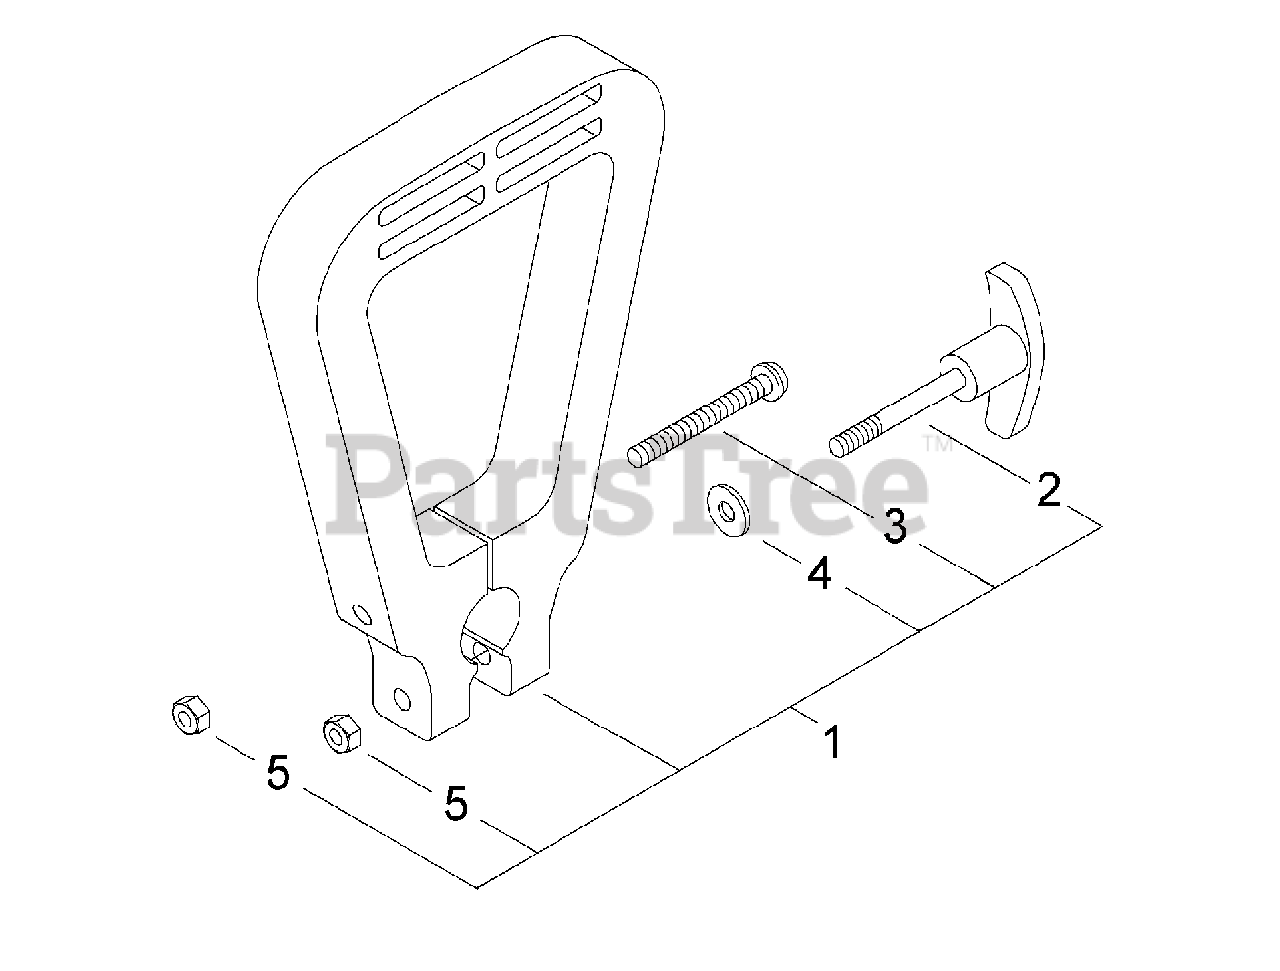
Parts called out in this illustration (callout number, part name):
1	HANDLE ASSY
2	THUMBSCREW
3	SCREW
4	WASHER
5	NUT - 6
